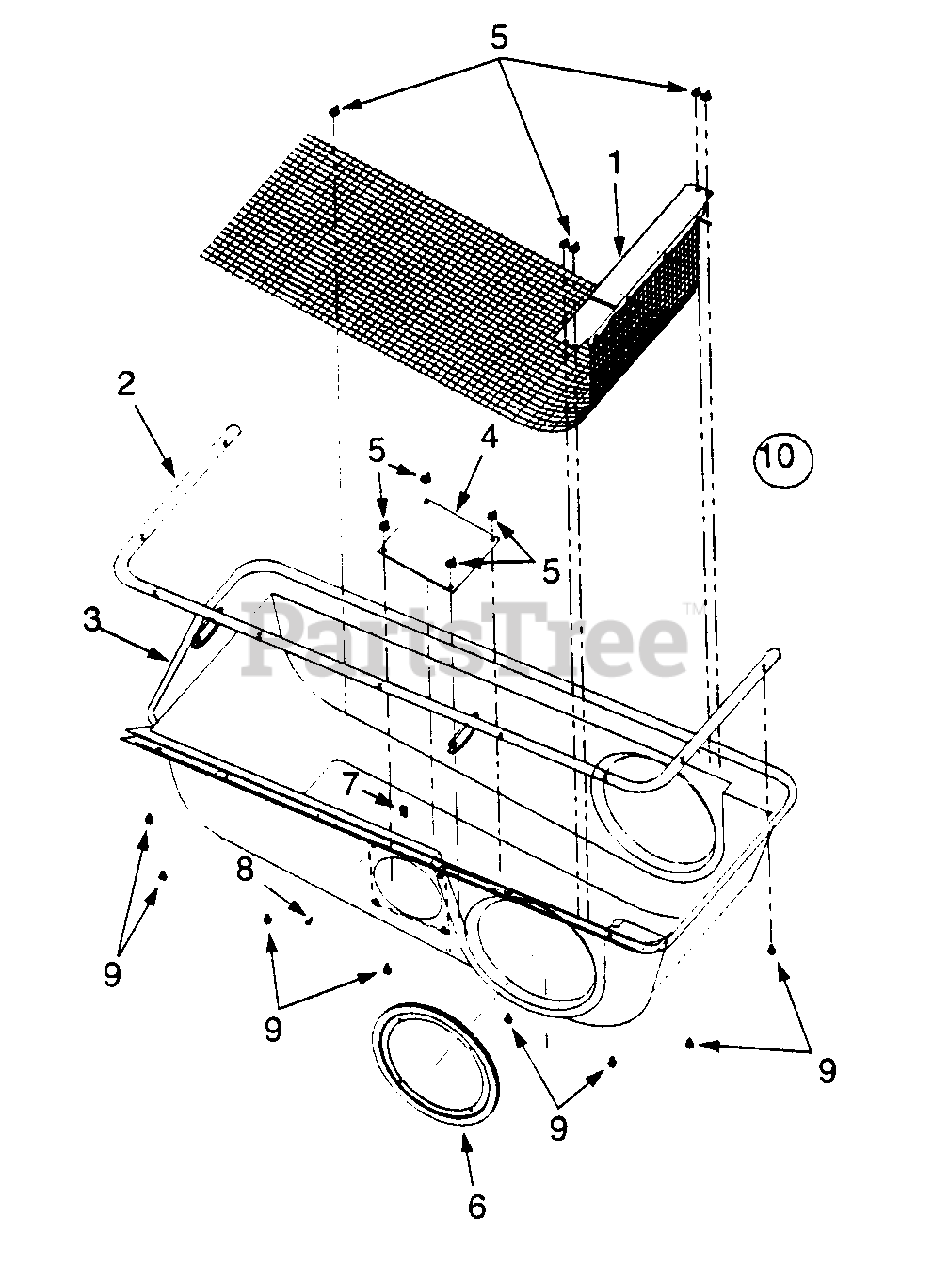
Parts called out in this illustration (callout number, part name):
3	Grass Catcher Cover
4	Plastic Plate
5	Zip Twist Fastener
6	Tube Seal
7	U-Type Speed Nut
8	Screw, #10-16 x 0.5"
9	Hex Screw, 1/4-20 x 0.5"
10	Grass Catcher Cover Assembly
